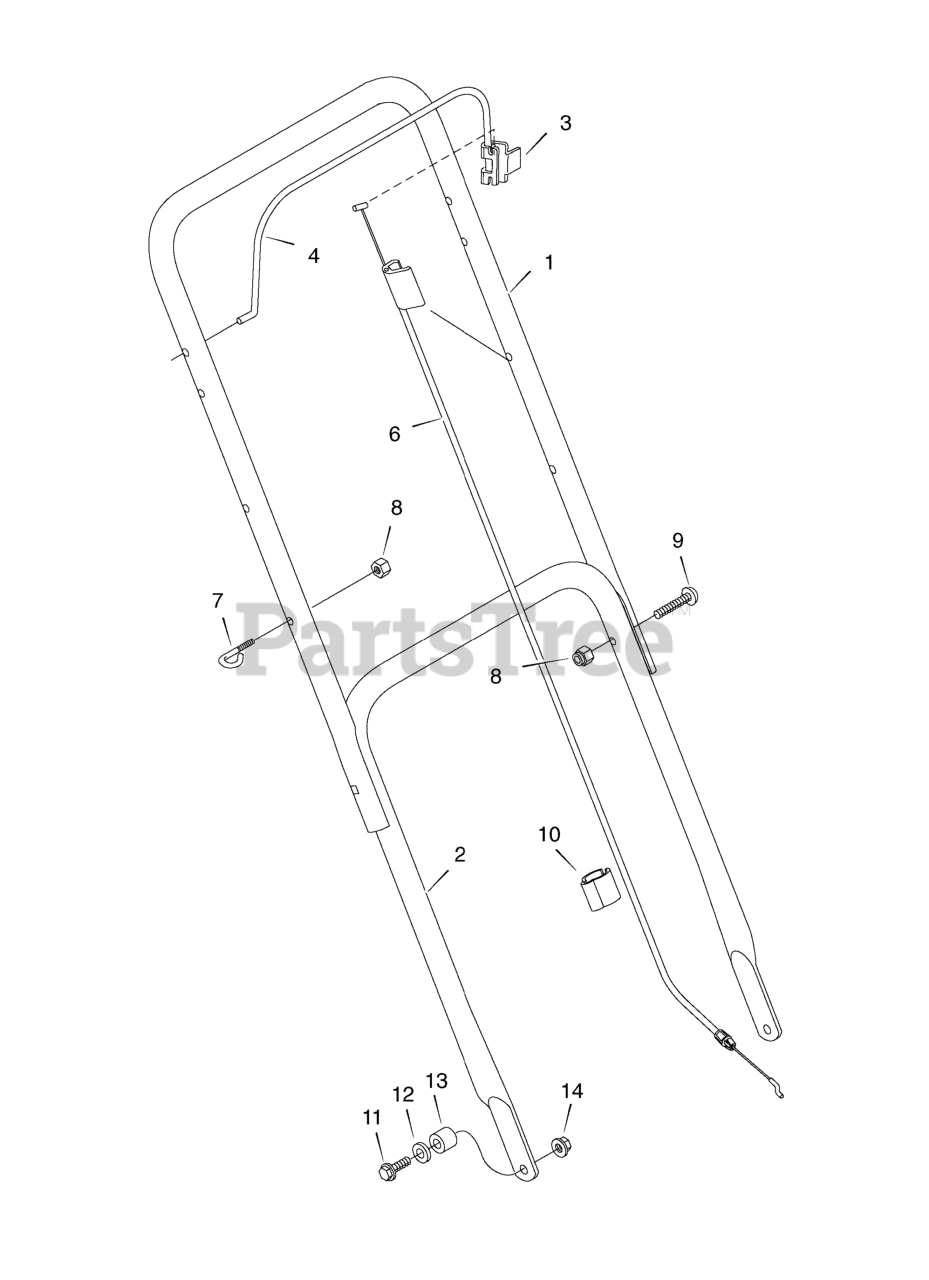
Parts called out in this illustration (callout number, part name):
1	HANDLE, Upper (Gray)
2	HANDLE, Lower (Gray)
3	BRACKET, Stop Lever
4	LEVER, Stop
6	CABLE, Engine Stop
7	GUIDE, Rope
8	LOCKNUT
10	CLIP, Cable
11	BOLT
12	WASHER
14	NUT
